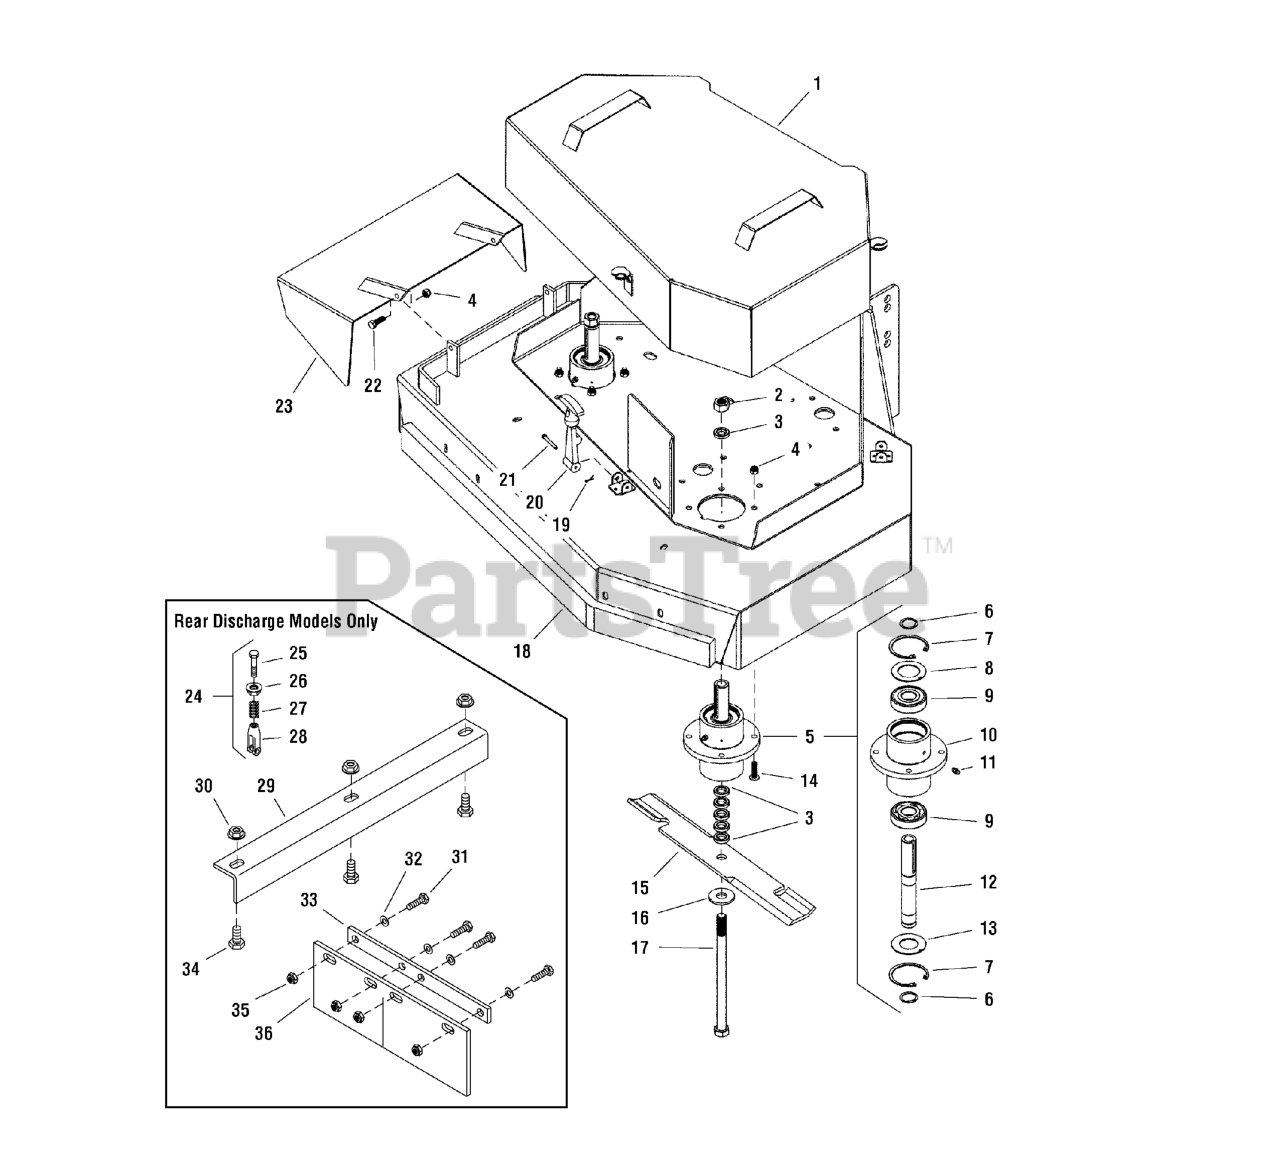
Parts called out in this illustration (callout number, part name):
1	GUARD, 36"
1	32" DECK GUARD
2	NUT, 5/8-11 Hex
3	SPACER, .63 x 1.06 x .23
4	NUT, 5/16-18 Hex Nylon Lock
5	SPINDLE ASSEMBLY, Complete
6	SPINDLE SHAFT
7	SNAP RING, External
8	SNAP RING, Internal
9	SPINDLE WASHER, Top
10	BEARING
11	SPINDLE HOUSING
12	GREASE FITTING
13	SPINDLE WASHER, Bottom
14	BOLT, Flange Head, 5/16-18 x 1-1/4
15	MOWER BLADE, 18"
15	MOWER BLADE, 18" SAND
15	MOWER BLADE, 16-1/4"
15	MOWER BLADE, 16-1/4" SAND
16	WASHER, 5/8" USS
17	BOLT, 5/8-11 x 9-1/2
18	DECK SHELL W/DECALS, 36" HW36 RD
18	DECK SHELL W/ DECALS, 32" HW32 RD
19	COTTER PIN
20	RUBBER LATCH
21	PIN, Clevis
22	BOLT, 5/16-18 X 1 GD5 YZ
23	DISCHARGE CHUTE
24	GUARD HOLD DOWN ASSEMBLY
25	BOLT, 5/16-24 X 2
26	NUT, 3/8-16 Hex Serrated Flange
27	SPRING, Guard Hold Down
28	CLEVIS, 5/16-24, Plastic
29	BAFFLE, 36"
29	BAFFLE, 32"
30	NUT, 3/8-16 Hex Serrated Flange
31	BOLT, 5/16-18 X 1 GD5 YZ
32	WASHER, 5/16" SAE
33	FLAP SUPPORT
34	BOLT, 3/8-16 X 3/4" GD5 CZ
35	NUT, 5/16-18 Hex Nylon Lock
36	RUBBER FLAP
